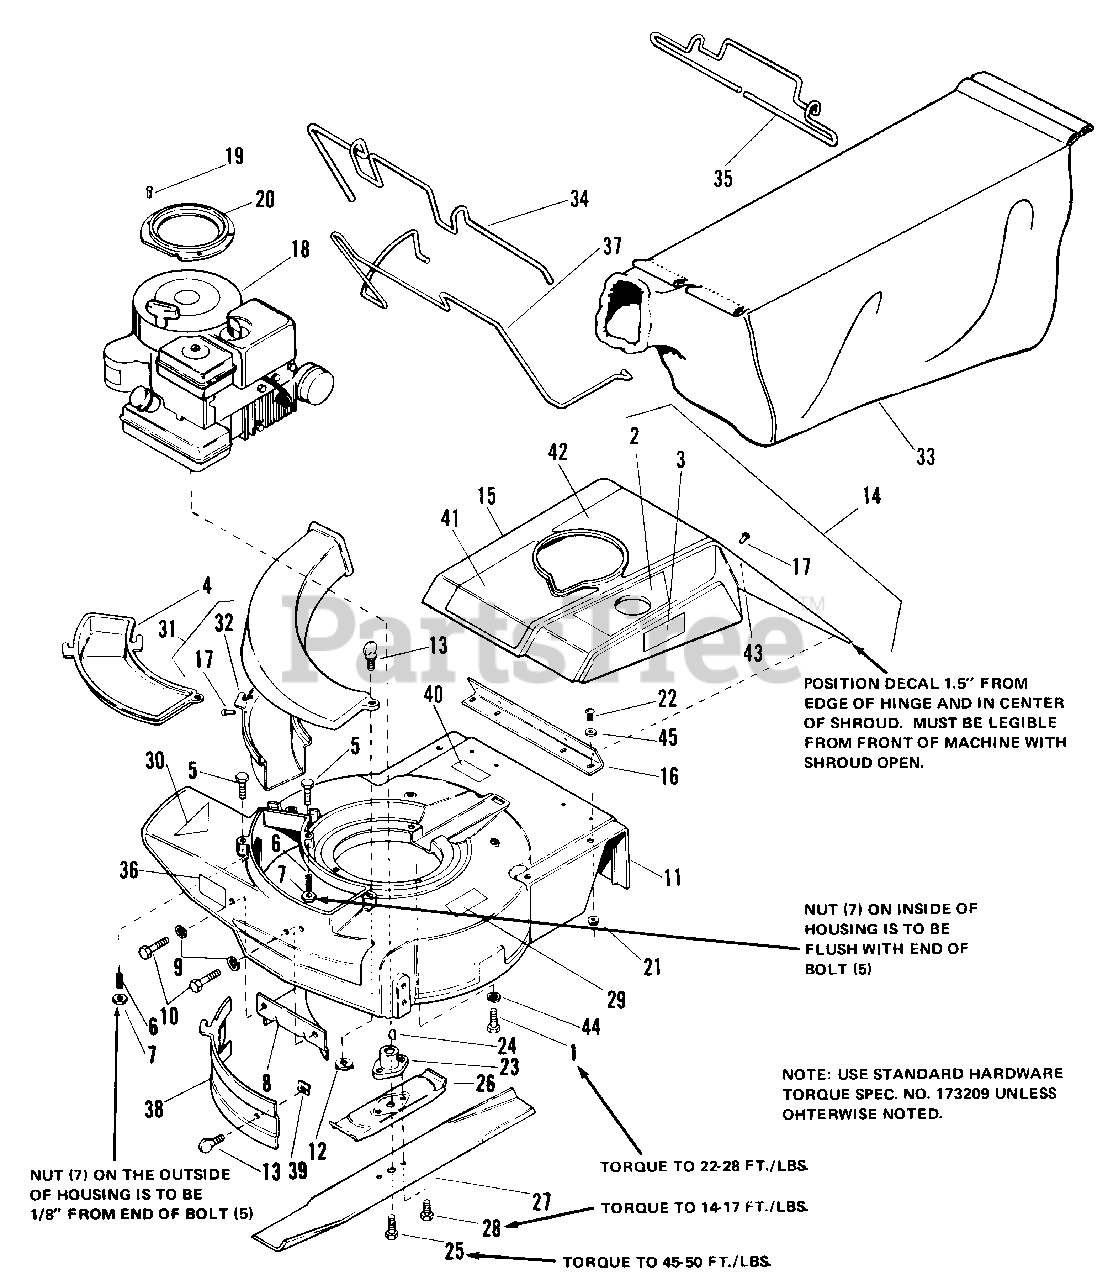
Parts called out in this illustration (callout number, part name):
1	SCREW, Taptite, 3/8-16 x 1-1/4
2	DECAL, Caution
3	DECAL, 1021
4	PLATE, Cover
5	SCREW, Special
7	NUT, Hex, Full, Lock, 1/4-20
8	GUARD ASSY, Stone
9	LOCKWASHER, 1/4
10	CAPSCREW, Hex, 1/4-20 x 1/2
11	HOUSING, 21"
12	NUT, Speed, Special, 1/4-20
13	SCREW, Wing, 1/4-20 x 5/8
14	SHROUD ASSY (Inc. Ref. Nos. 15, 16, 17)
15	SHROUD
17	RIVET, 3/16 x 5/16
18	ENGINE, 3.5 HP Briggs & Stratton.
19	RIVET, Pop, 3/32 x .337
20	SUPPORT, Ring
21	NUT & WASHER ASSY, No. 10-32
22	CAPSCREW, Hex Hd., No. 10-32
23	ADAPTOR, Blade
24	KEY, Woodruff, No. 6
25	CAPSCREW, Hex, 3/8-24 x 1-1/2
26	STIFFNER, Blade
27	BLADE, 21"
28	SCREW, 5/16-18 x 1
29	DECAL, Instructions
30	DECAL, OPEI
31	CHUTE ASSY
32	DEFLECTOR
33	GRASS BAG
34	SUPPORT, Bag, Front
35	SUPPORT, Bag, Rear
36	DECAL, Numerial, 21"
37	ROD, Support Bag
39	NUT, Speed, 1/4-20
40	I.D. PLATE
41	DECAL, Shroud
42	DECAL, Shroud
43	DECAL, Speed Control
44	LOCKWASHER, Ext. Tooth, 3/8
45	WASHER, Plain, 3/16
